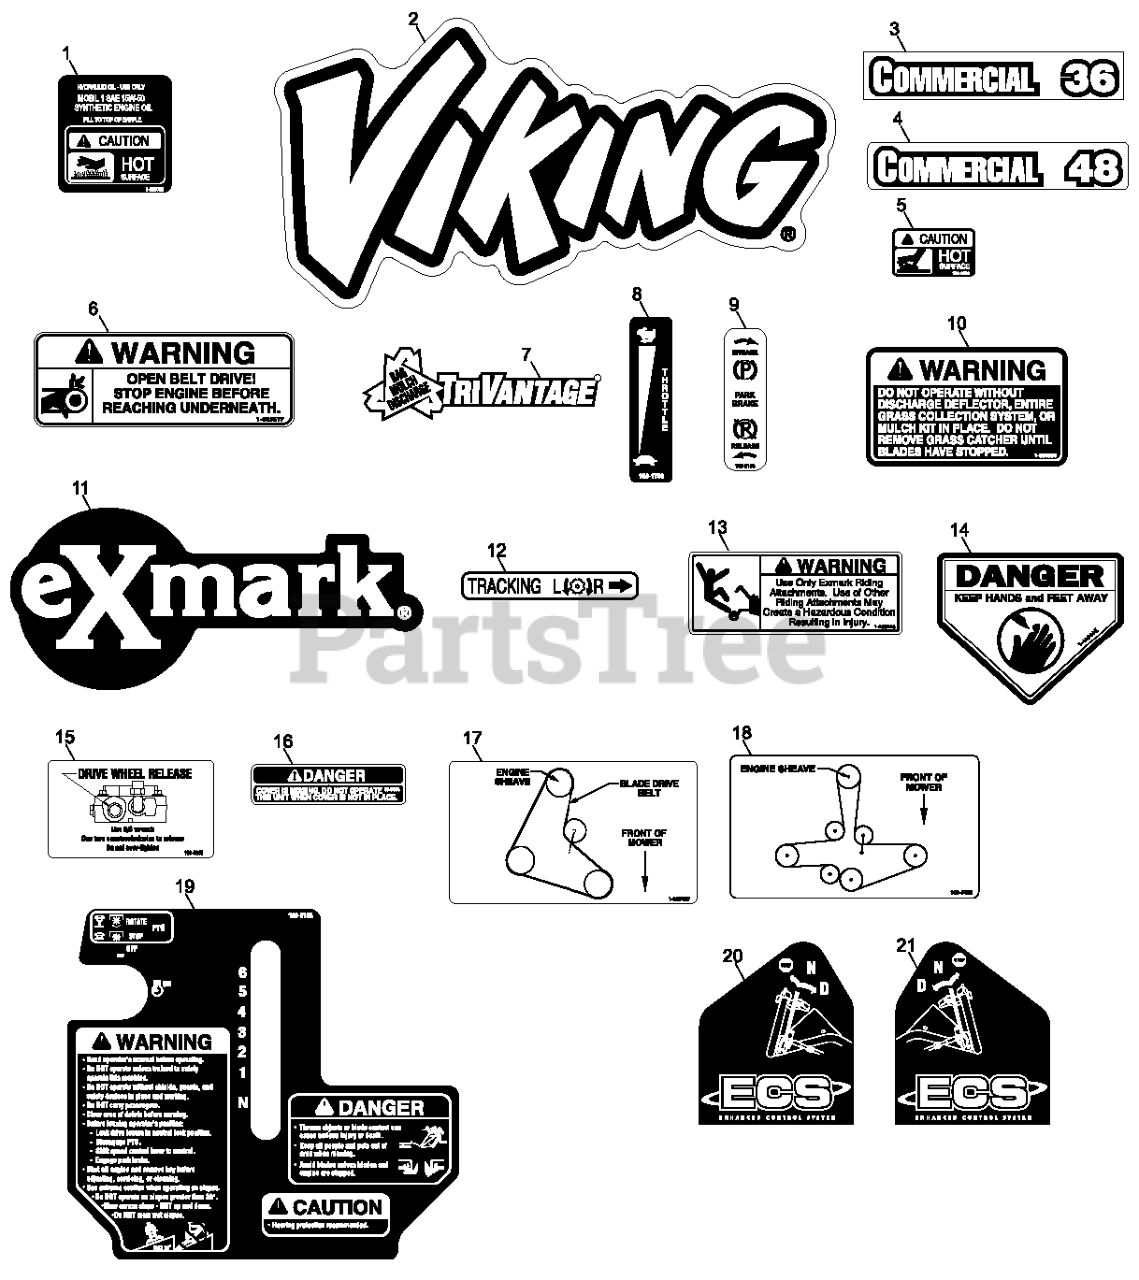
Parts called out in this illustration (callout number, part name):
2	DECAL,VH MODEL
3	DECAL,COMMERCIAL 36
4	DECAL,COMMERCIAL 48
5	DECAL-CAUTION
6	DECAL,BELT DRIVE
8	DECAL,THROTTLE ONLY
9	DECAL-BRAKE, PARK
10	DECAL-WARNING, DISCHARGE
11	DECAL,EXMARK LOGO
12	DECAL,TRACKING ADJUST
13	DECAL,SULKY WARNING
14	DECAL-DANGER
15	DECAL,DRIVE RELEASE
16	DECAL-COVER, MISSING
17	DECAL,BELT ROUTING 32/36
18	DECAL,BELT ROUTING
19	DECAL,CONSOLE VH ECS
20	DECAL,LH ECS INSTRUCTION
21	DECAL,RH ECS INSTRUCTION
